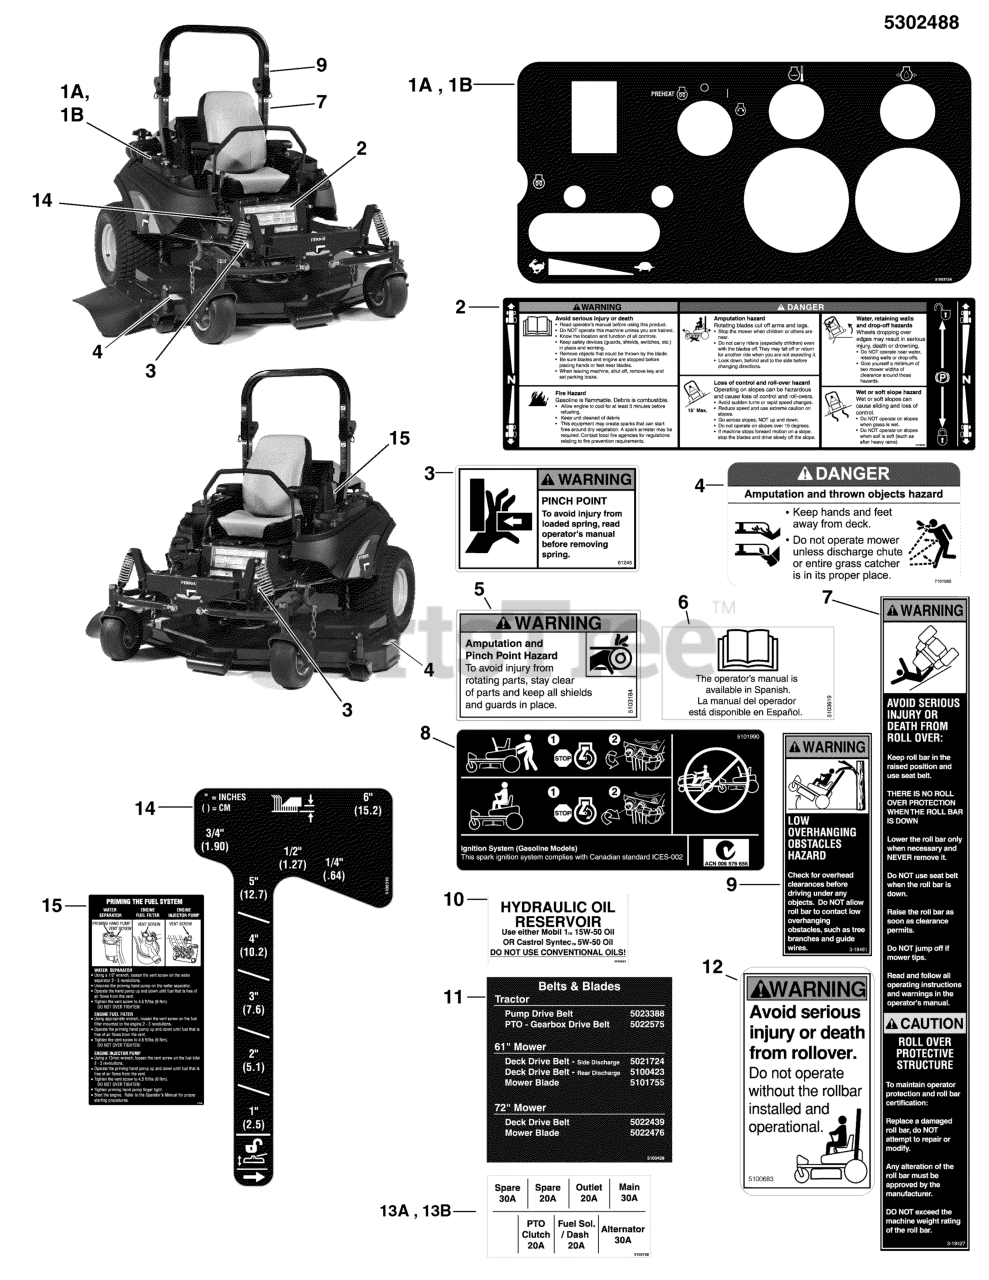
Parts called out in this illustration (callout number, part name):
1A	DECAL, CONTROL PANEL, IS5100Z
1B	DECAL, CONTROL PANEL, IS5000Z
2	DECAL, MAIN SAFETY
3	DECAL, PINCH POINT
4	DECAL, DANGER DO NOT OPERATE W/O DEFLECT
5	DECAL, WARNING, HAND IN BELT, ENG ONLY
6	DECAL, MANUAL AVAIL IN SPANISH
8	DECAL, CZT HYDRO RELEASE
9	DECAL, WARNING OVERHANG, ROPS
10	DECAL-OIL RESERVOIR
11	DECAL, BELT & BLADE, IS5100iCD, HYD LIFT
12	DECAL, WARNING, ROLL BAR
13A	DECAL, FUSE LOCATION
13B	DECAL, FUSE LOCATION, IS5100Z, MECH LFT
14	DECAL, HEIGHT OF CUT, IS5000Z
15	DECAL, PRIMING INSTRUCTIONS
